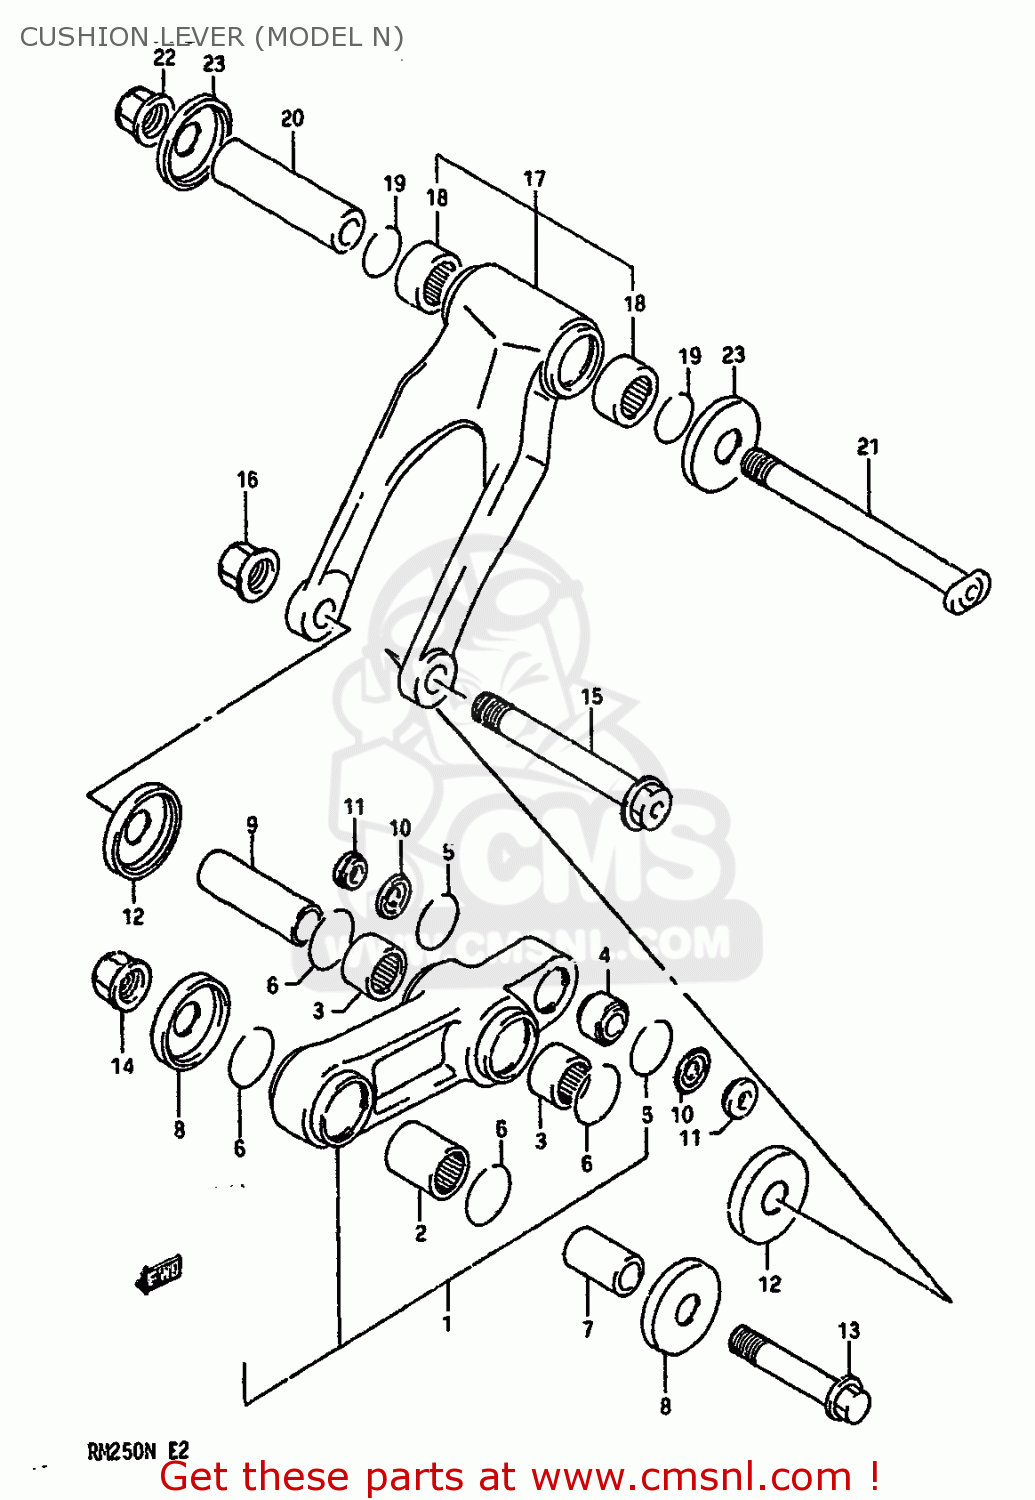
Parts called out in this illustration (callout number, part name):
1	LEVER SET,REAR CUSHION
2	BEARING(20X27X25)
3	BEARING(21X27X20)
4	BEARING,RR CUSHION LEVER RR
5	RING,BEARING STOPPER
6	CIRCLIP
7	SPACER,RR CUSHION LEVER FR
8	SEAL,REAR CUSHION LEVER
9	SPACER,REAR CUSHION LEVER,C
10	SEAL,RR CUSHION LEVER RR DUST
11	SPACER,RR CUSHION LEVER RR
12	SEAL,REAR CUSHION LEVER
13	BOLT,RR CUSHION LEVER FR
14	NIT
15	BOLT,RR CUSHION LEVER CTR
16	NUT
17	LEVER SET,REAR CUSHION
18	BEARING(21X27X20)
19	CIRCLIP
20	SPACER,RR CUSHION ROD
21	BOLT,RR CUSHION ROD
22	NUT
23	SEAL,REAR CUSHION LEVER
24	SEAL,RR CUSHION LEVER
